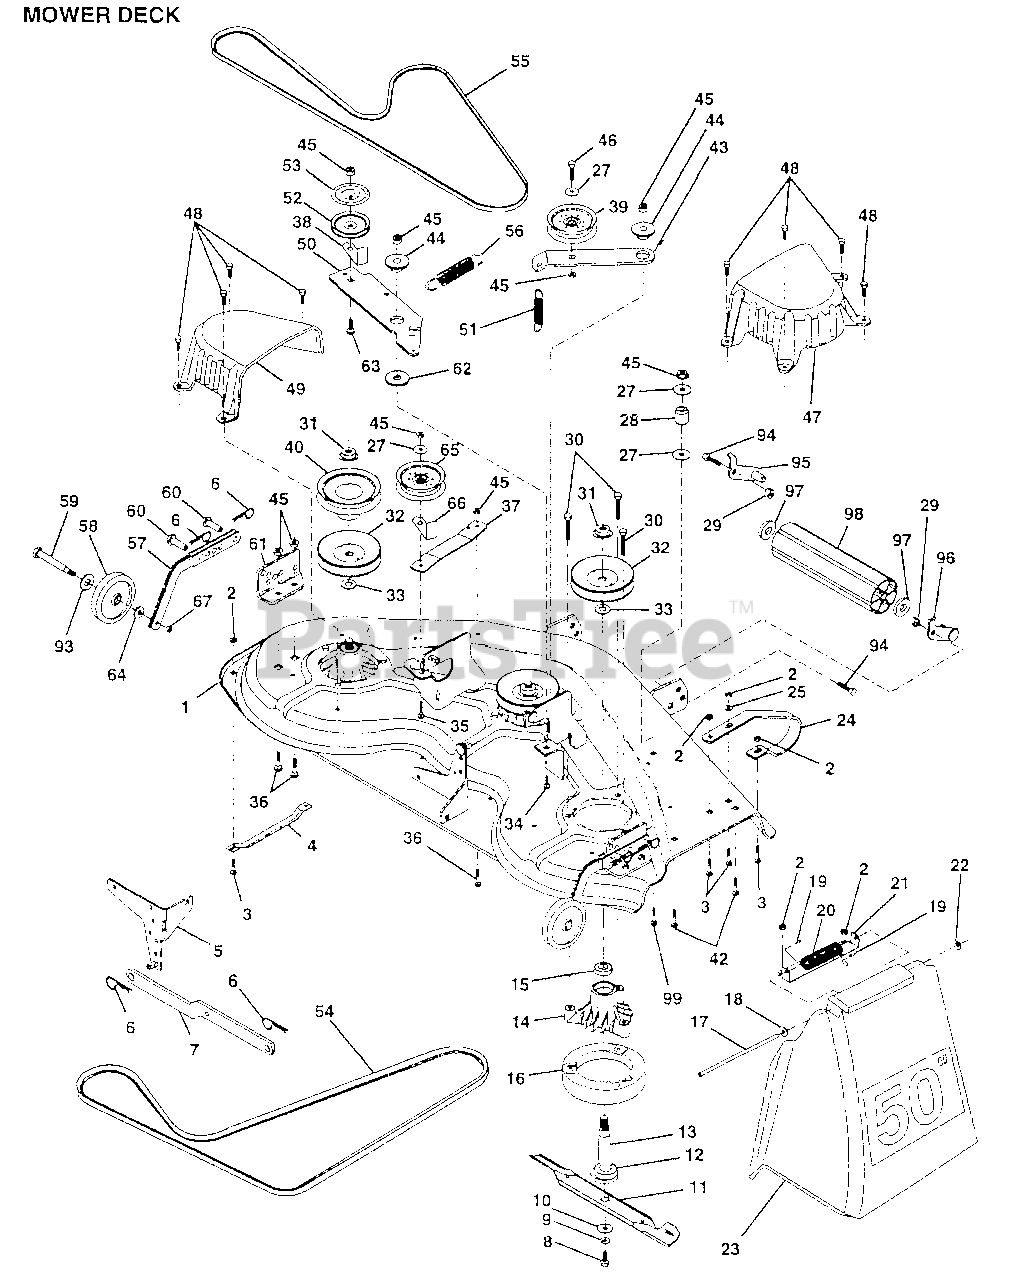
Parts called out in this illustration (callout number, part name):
1	DECK ASM MWR 50VT
4	RUNNER-LH M
5	BRKT.ASM.SW.44/50
8	BLADE BOLT
10	WASHER.HARD.BLADE
11	"BLADE.50"" HD"
12	BEARING.BALL
13	SHAFT.ASM.W/BRNG
14	HOUSING.MAND.44.V
15	BEARING
16	STRIPPER RND MWR
17	ROD-HINGE T
18	WASHER
19	CAP-SLEEVE LT
20	SPRING TORSION
21	BRKT DEFLECTOR
22	NUT PUSH M
23	DEFLECTOR
24	"RUNNER RH 50"" DK"
25	WASHER M
27	WASHER
29	NUT
33	WASHER
34	BOLT.3/8-14X1.25
35	BOLT
36	BOLT D
37	STIFFENER.ARM.IDL
39	FLAT IDLER PULLEY
40	"PULLEY.DRIVEN.44"""
42	BOLT
43	"ARM.IDLER.SEC.44"""
44	SPACER RETAINER
47	"COVER.MAND.RH.44"""
48	SCREW.1/4-20X5/8
49	COVER.MANDREL.LH
50	ARM.IDLER.PRIMARY
51	"SPRING.SEC.44""VEN"
52	PULLEY.IDLER.VGRO
53	SHIELD.IDLER.44.V
54	BELT V PRIM 50
55	BELT-V.SEC.46.KEL
56	SPRING.EXT.DECK.
57	BAR.ASM.GUAGE.WHL
58	WHEEL.GAGE.BLK.PL
59	BOLT M
60	PIN.CLEVIS
61	BRACKET.GUAGE.WHL
62	HARDENED WASHER
63	BOLT.3/8-16X1.50
64	WASHER
65	IDLER-FLAT T
67	LOCKNUT
93	WASHER
94	BOLT
97	WASHER
99	BOLT
